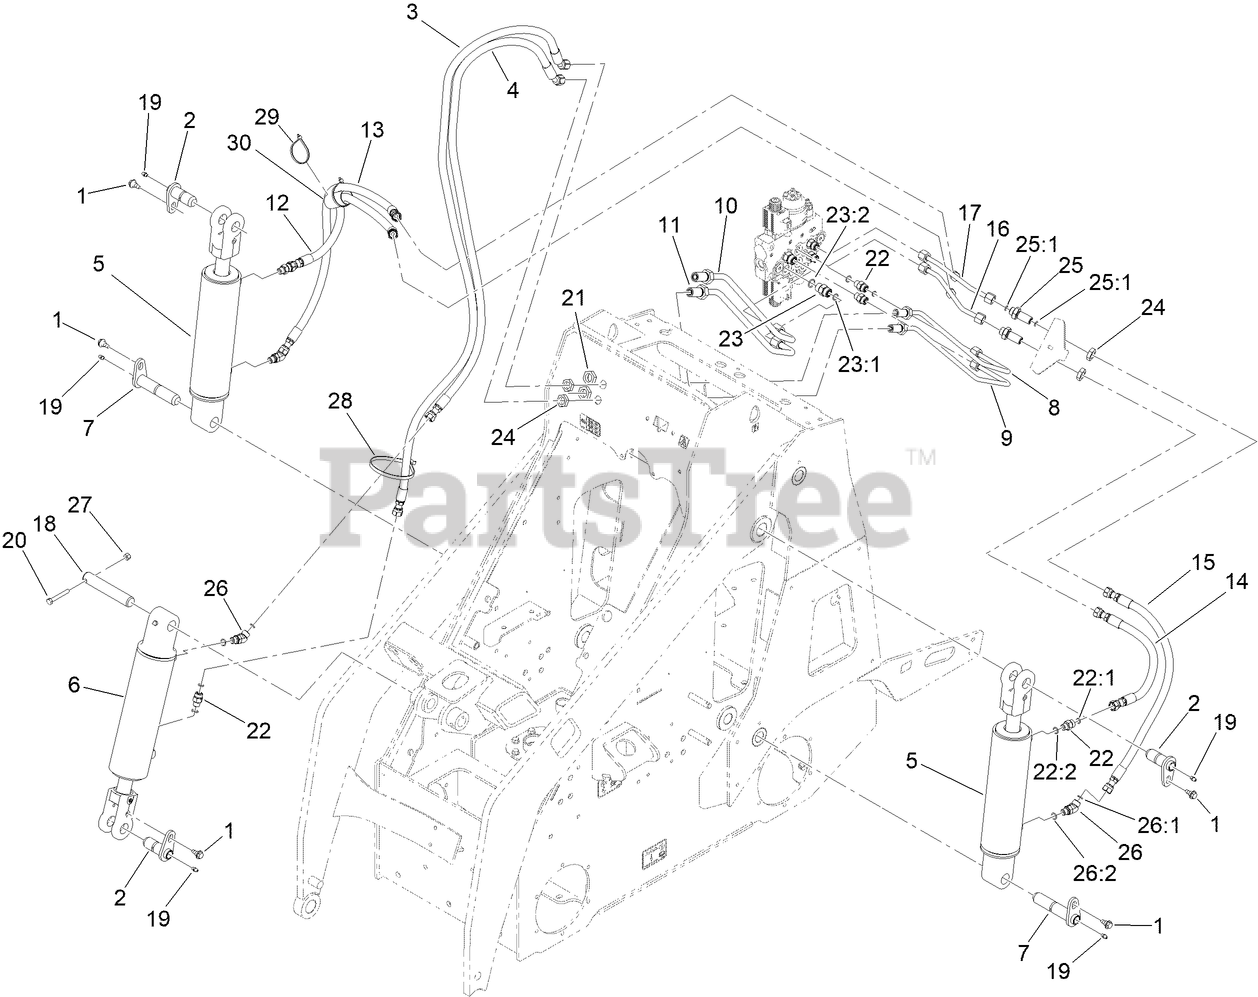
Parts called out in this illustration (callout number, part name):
1	BOLT-SHOULDER
2	PIN-PIVOT
3	HOSE ASM-HYD
4	HOSE ASM-HYD
5	CYLINDER-HYDRAULIC
6	HYD-CYLINDER
7	PIN-PIVOT
8	HYDRAULIC TUBE ASM
9	HYDRAULIC TUBE ASM
10	HYDRAULIC TUBE ASM
11	HYDRAULIC TUBE ASM
12	HOSE ASM-HYD
13	HOSE ASM-HYD
14	HOSE ASM-HYD
15	HOSE ASM-HYD
16	HYDRAULIC TUBE ASM
17	HYDRAULIC TUBE ASM
18	PIN-LOCKING
19	FITTING-GREASE
20	SCREW-HH
21	NUT-BULKHEAD
22	FITTING-STRAIGHT
22:1	O-RING
22:2	O-RING
23	FITTING-STRAIGHT
23:1	O-RING
23:2	O-RING
24	NUT-LOCK
25	FITTING-STRAIGHT, BULKHEAD
25:1	O-RING
26	FITTING-ELBOW, 45 DEG
26:1	O-RING
26:2	O-RING
27	NUT-LOCK, NI
28	TIE-CABLE
29	TIE-CABLE
30	PROTECTOR-HOSE
